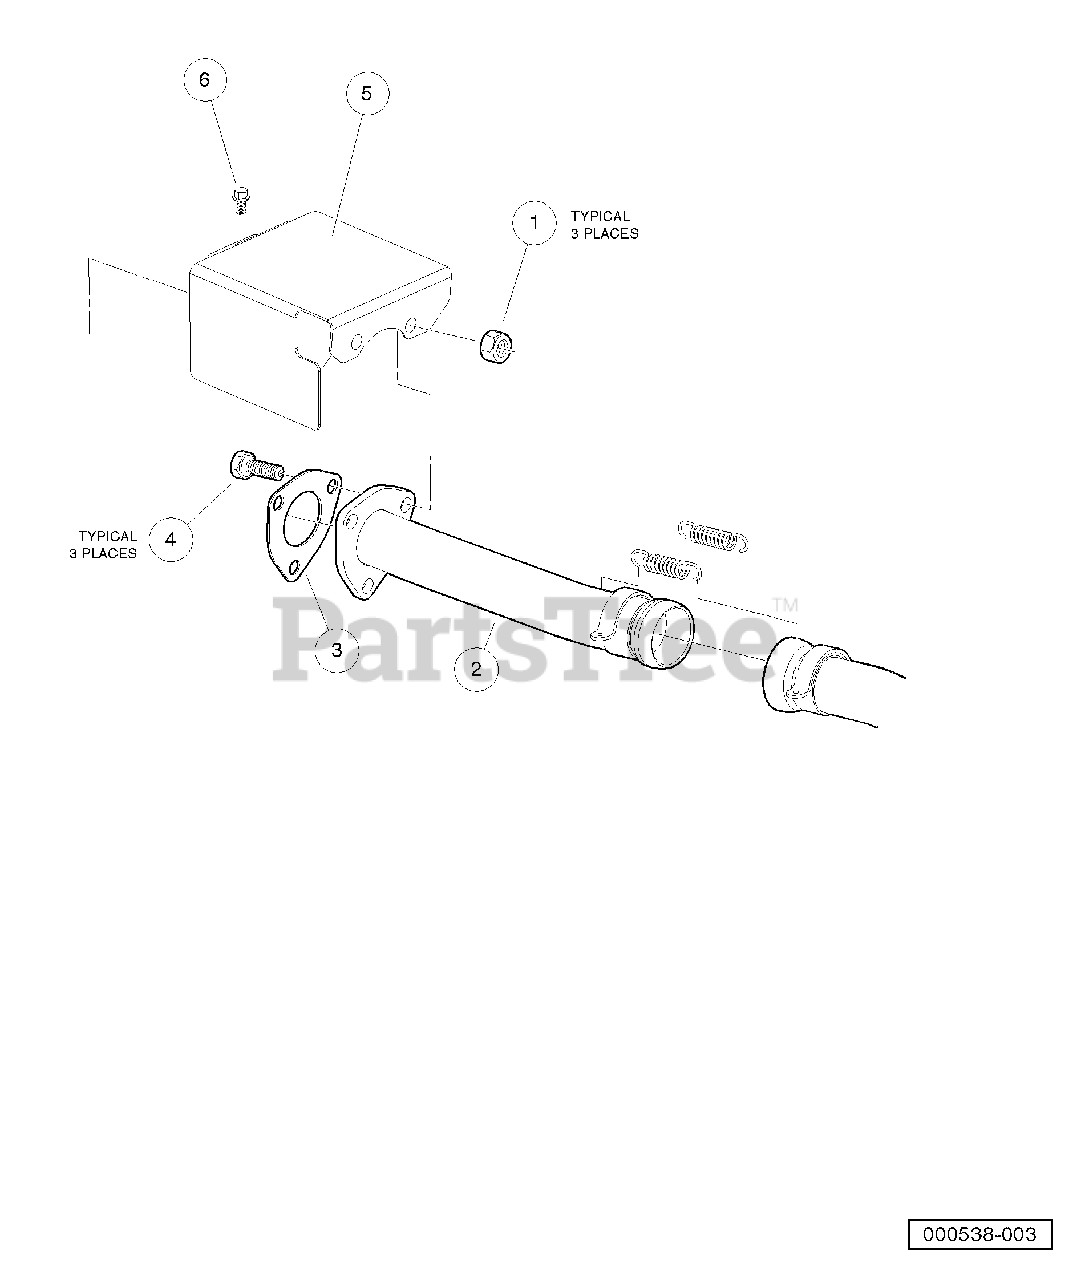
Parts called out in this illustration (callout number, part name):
1	Nut,m8,all Metal Lock
2	Pipe, Exhaust Diesel Main
3	Gasket, Exhaust Diesel
4	Bolt, M8 X 1.25 X 40 with Loctite
5	Shield, Diesel Exhaust
6	Bolt, D722, Exhst Manfld Cover
